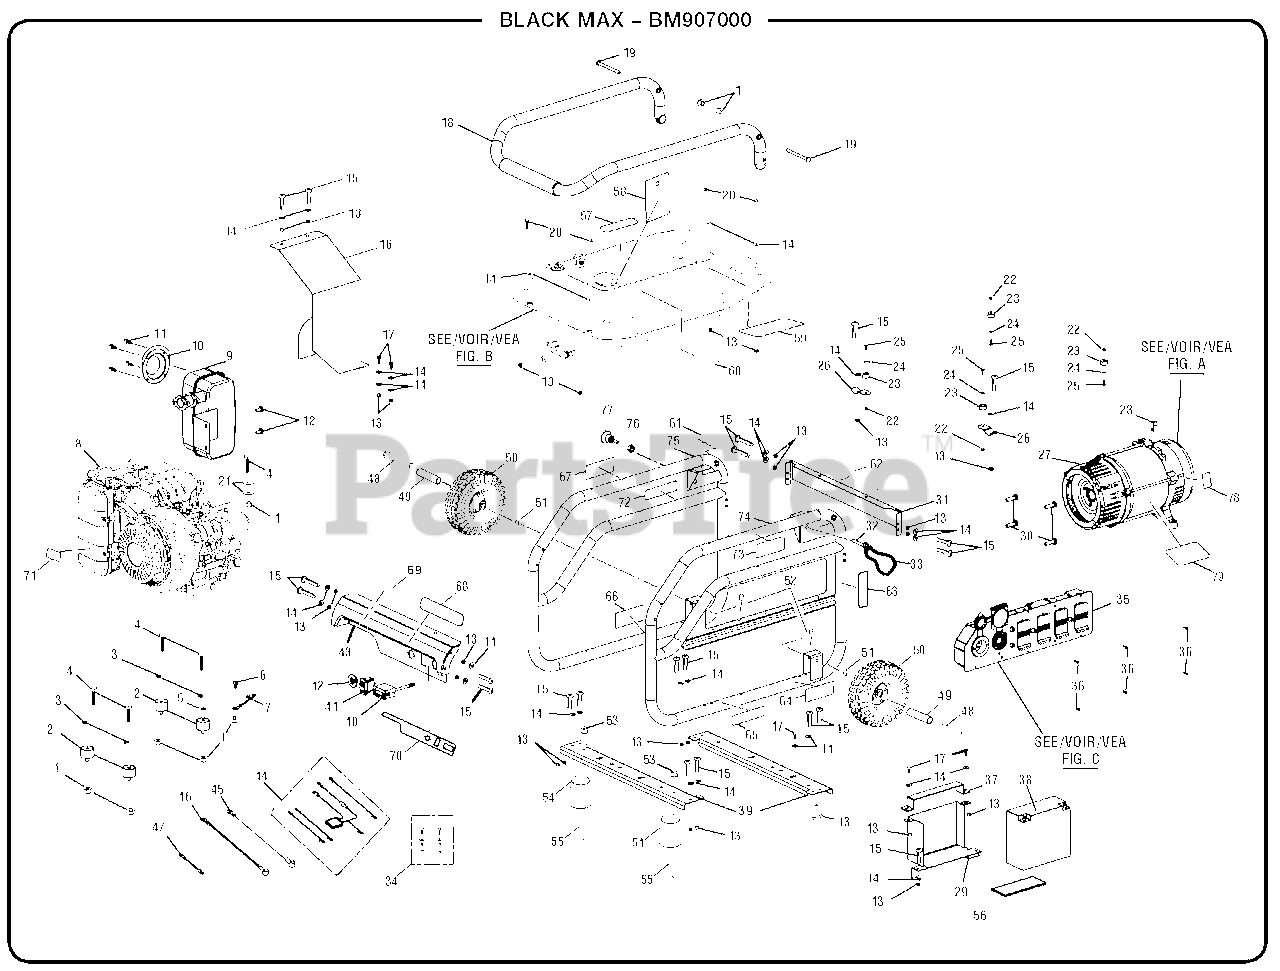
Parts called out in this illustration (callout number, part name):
1	Lock Nut (M8 x 1.25 in.)
3	Washer (M8)
4	Bolt (M8 x 35 mm, Hex Hd.)
5	Star Washer (M8)
6	Bolt (M8 x 15 mm)
7	Ground Wire Assembly
10	Spark Arrestor
11	Screw (8-32 x 3/8 in.)
12	Bolt (5/16-24 x 0.6 in.)
13	Lock Nut (M6)
14	Washer (M6)
15	Screw (M6 x 50 mm, Torx Hd.)
16	Heat Shield
17	Bolt (M6 x 16 mm)
18	Handle Assembly
19	Handle Pivot Bolt (M8 x 98 mm, Flat Hd.)
20	Bolt (M6 x 25 mm, Torx Hd. T30)
21	Washer (5/16 in.)
23	Rubber Bumper
24	Washer (M4)
25	Screw (M4 x 12 mm)
26	Handle Rest Tab
27	Generator Head w/AVR
28	Ground Lug
29	Battery Tray
30	Bolt (3/8-16 x 1 in.)
31	Fuel Tank Support (Back)
32	Handle Lock Pin
34	Fastener Kit (Wiring)
35	Control Panel Assembly
36	Screw (6-20 x 3/8 in., Pan Hd.)
37	Battery Bracket
38	Battery
39	Frame Crossbar
40	Hour Meter
41	Engine Switch
42	Fuel Valve
43	Fuel Tank Support (Front)
44	Wiring Harness
45	Battery Cable (Black)
46	Battery Cable (Red)
47	Bonding Wire
51	Washer (M10)
52	Hitch Pin
53	Lock Nut (M8 x 1.25)
54	Rubber Foot
55	Bolt (M8 x 45 mm, Hex Hd.)
57	CPSC Label
58	Warning Hangtag
59	Danger Label
60	E85 Label
61	Handle Release Label
62	Ground Warning Label
63	Lock Pin Label
64	Inquiries Label
65	Lubricant Label
66	Combustion Label
67	Fire Distance Label
68	Logo Label
69	Honda Label
70	Start Label
71	Electric Start Label
72	Hot Surface Label
73	Fire Danger Label
74	Frame (Right)
75	Frame (Left)
76	Hex Jam Nut (1/2-20)
77	Handle Release Pin
78	Ground Label
79	Data Label
